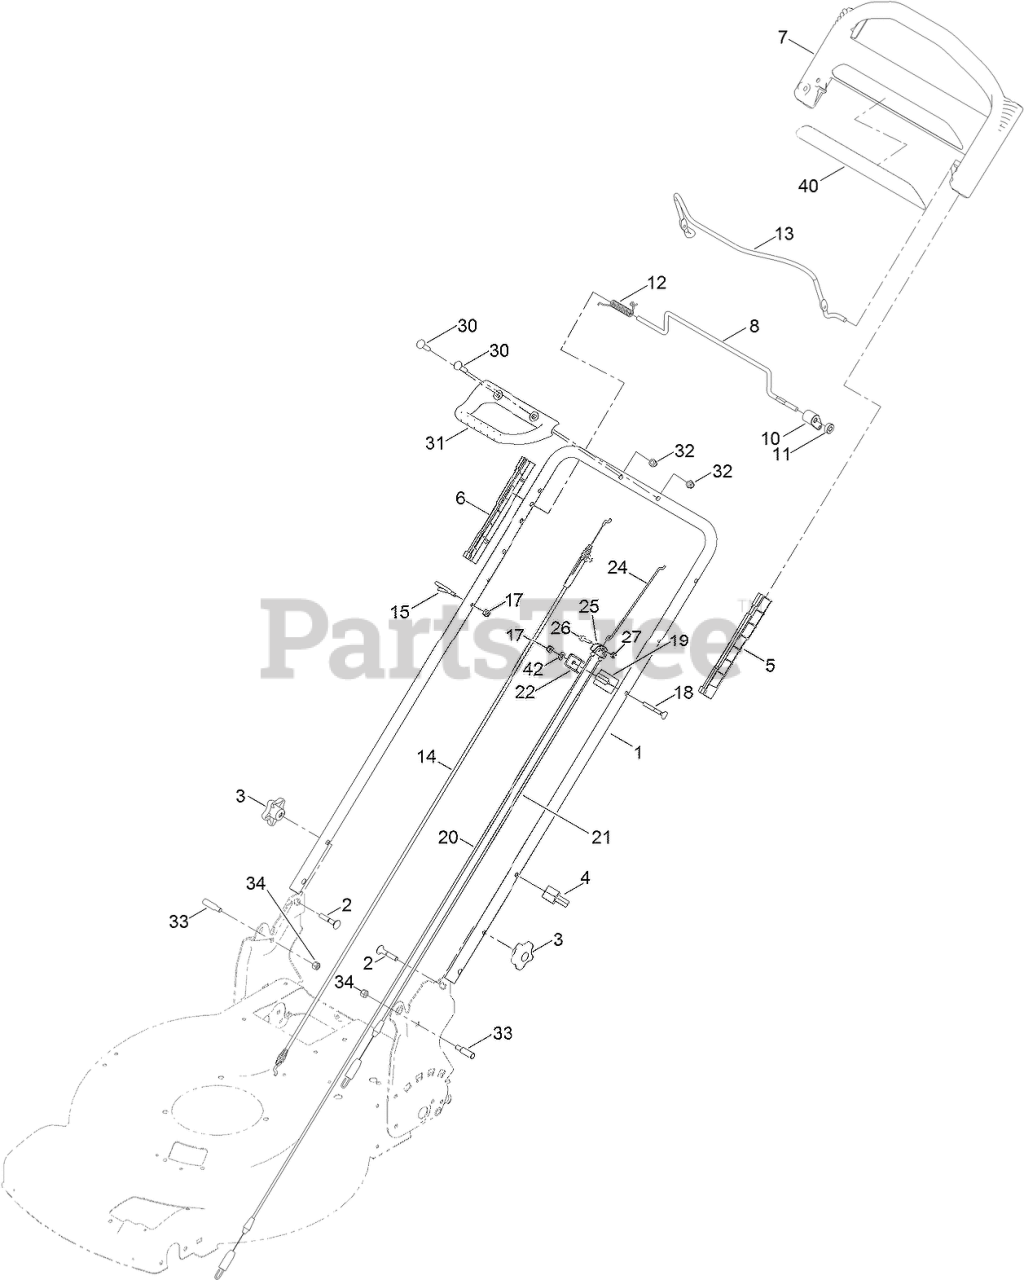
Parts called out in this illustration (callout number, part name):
2	SCREW-CARR
3	KNOB-HANDLE
4	GUIDE-CABLE
5	GUIDE-LH
6	GUIDE-RH
7	HANDLE-CONTROL
8	BAR-CONTROL, TRACTION
10	LEVER-TRACTION
11	SPACER
12	SPRING-TORSION
13	BAIL-BRAKE
14	CABLE-BRAKE
15	GUIDE-ROPE
17	NUT-HEX
18	SCREW-HANDLE
19	MOUNT-CABLE, TRACTION
20	CABLE-TRACTION, FRONT
21	CABLE-TRACTION, REAR
22	CLAMP-CABLE
24	LINKAGE-EQUALIZER
25	YOKE-CABLE
26	SCREW-SHOULDER
27	NUT-HEX
30	BOLT-CARRIAGE
31	HANDLE-ASSIST, TRACTION
32	NUT-ACORN
33	BOLT-SHOULDER
34	NUT-HEX
40	DECAL-DRIVE, AUTOMATIC
42	WASHER-FLAT
